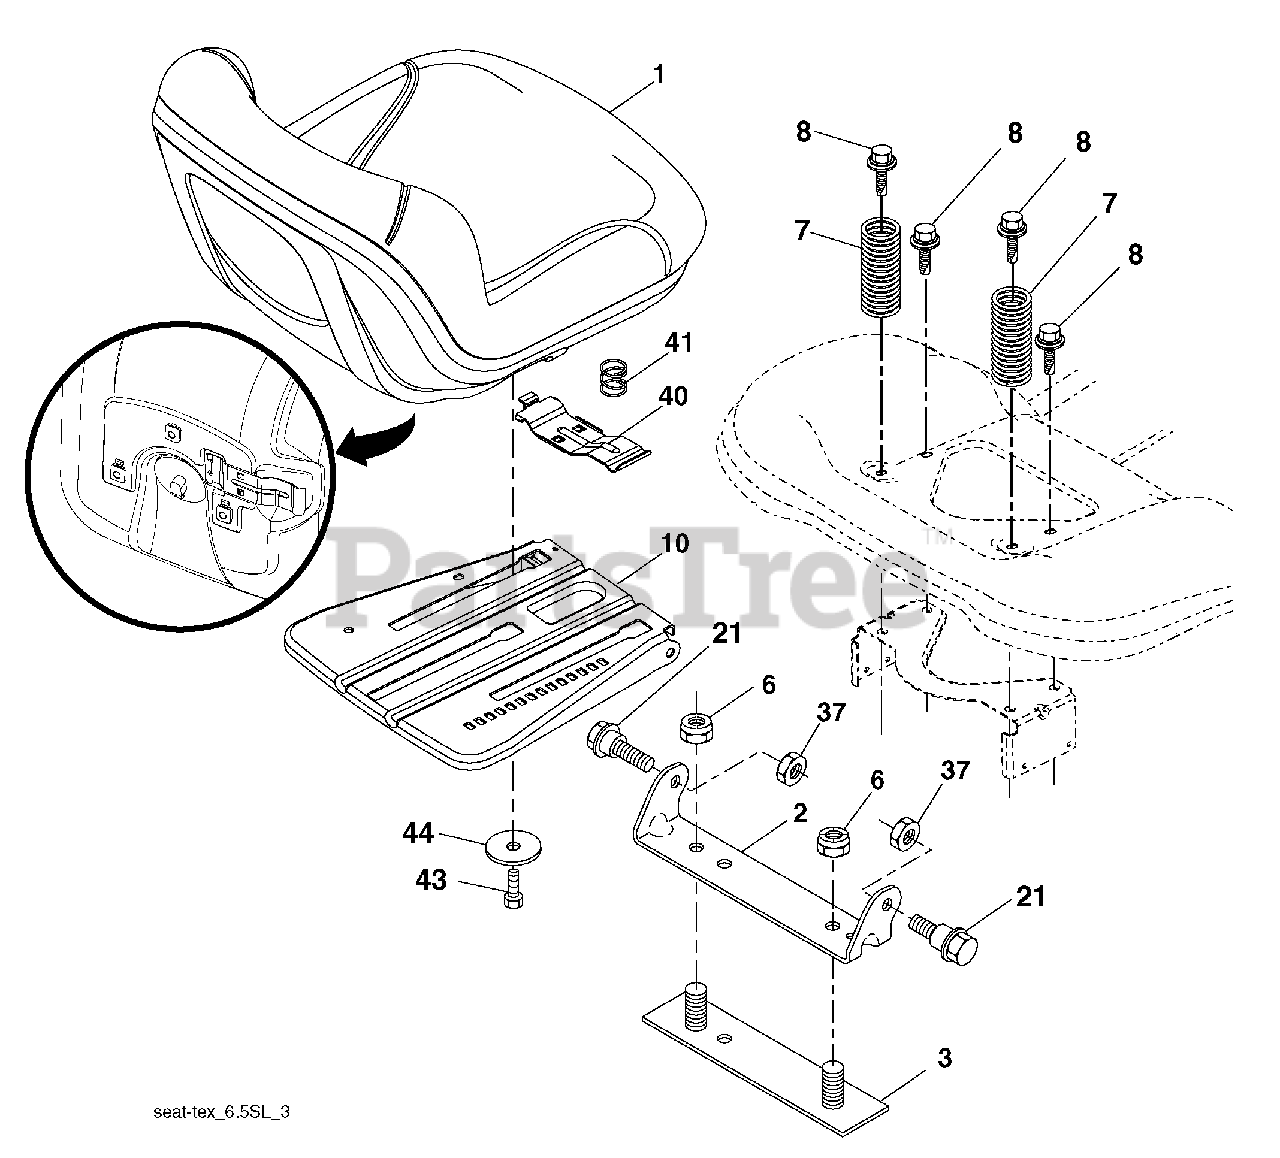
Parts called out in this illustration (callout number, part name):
1	Seat
2	Bracket Pivot Fender
3	Strap, Asm. Fender
6	Nut, Lock w/Ins. 3/8-16 unc
7	Spring, Seat Cprsn.
8	Bolt 5/16-18 unc x 3/4 w/Sems.
10	Pan, Seat
21	Bolt, Shoulder 5/16-18
37	Nut, Lock 5/16-18 unc
40	Handle Slide Seat
41	Spring Latch Seat
43	Bolt Fin. Hex 3/8-16 unc x 3/4
44	Washer 13/32 x 2-3/8 x 12 Ga.
